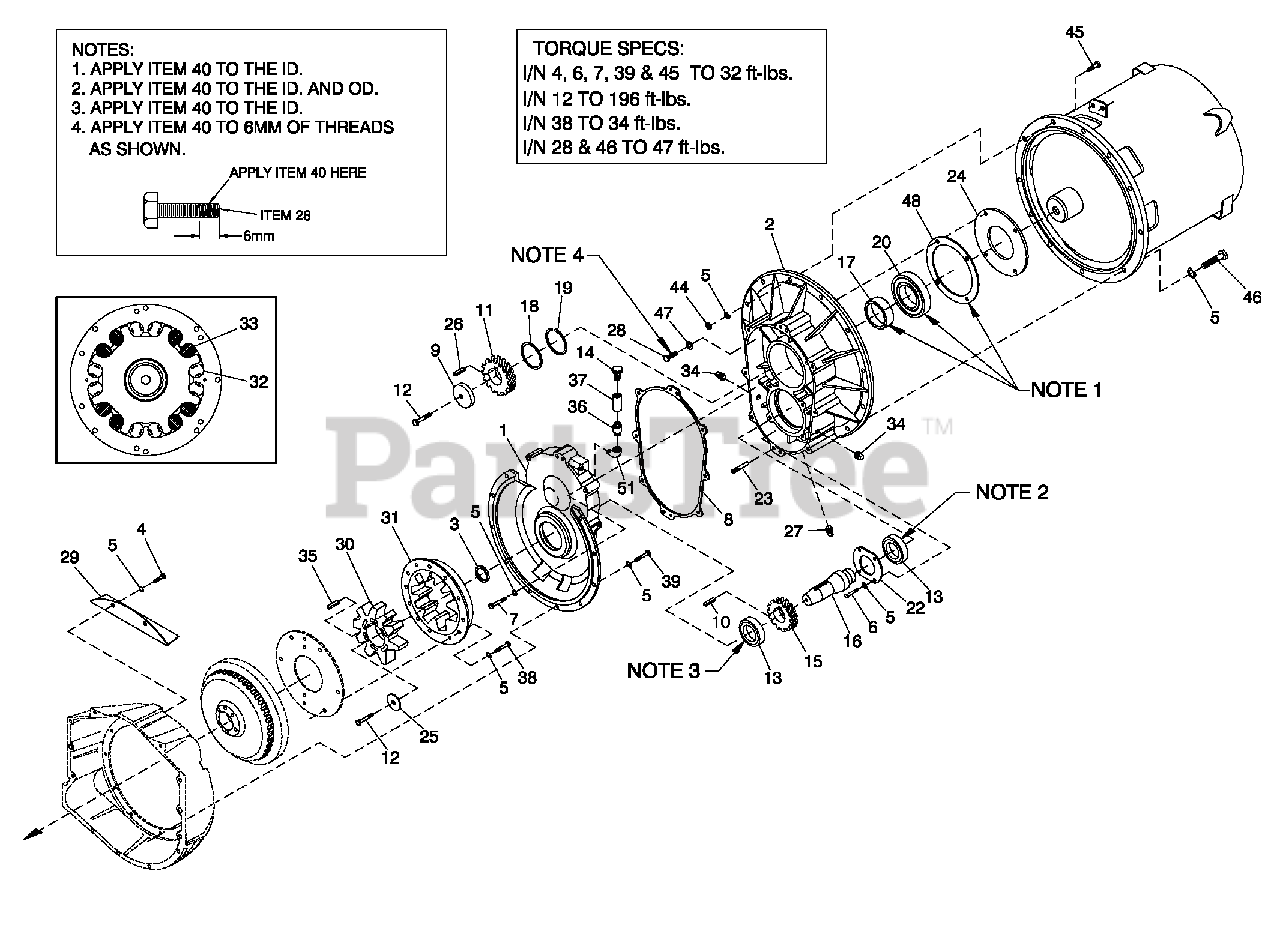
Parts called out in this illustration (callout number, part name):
1	GEAR CASE ENG. MACHINED
2	GEAR CASE ALT. MACHINED
3	SEALOIL
4	S CREW HHC M10l1.5X 20 G8.8
5	WASHER LOCK M10
6	S CREW HHC M10l1.5X 25 G8.8
7	S CREW HHC M10l1.5X 70 G8.8
8	GASKET 390 GEAR BOX
9	S PACER .69 X 2.75 X .37 ST/ZNC
10	KEY 1 0 X 1 6 X 4 6
11	GEAR OUTPUT 1.65:1
12	SCREW HHC M16-2.0X 35 G10.9
13	BALLBRG65X 120X23
14	BREATHER
15	GEAR INPUT 1.65:1
16	GEAR INPUT 2:1 50HZ390
17	SHAFT 390 INPUT GEAR
18	COLLAR HARDENED
19	SEALOIL
20	SNAP RING INT 120MM
22	BEARING #6213 SEALED
23	PLATE INTRNLBRG RET
24	PIN DOWEL M8X 24
25	PLATE BEARING THRST
26	SPACER STRESSPROOF
27	KEY 1 0 X 1 6 X 4 0
28	PLUG PIPE 3/8"MAGNETIC
29	SCREW HHFC M10-1.5X 25 G10.9
30	COVER GEARBOX GUARD
31	COUPLING INNER DRAWN
32	COUPLING OUTER MACHN
33	DAMPER GB CPLRVIBRA
34	DAMPER GB CPLRVIBRA
35	PLUG STD PIPE 3/8 STEEL SQ HD
36	KEY 1 0 X 1 6 X 5 0
37	NIPPLE PIPE3/8NPTX 3-1/2
38	COUPLING FULL 3/8-18
39	SCREW HHC M10l1 .5X 25 G8.8
40	RETAINING COMPOUND
44	NUTHEXM10-1.5G8 YEL CHR
45	SCREW HHC M10l1 .5X 60 G8.8
46	SCREW HHC M10l1 .5X 40 G10.9
47	WAS HER FLAT M10 S EALING COPPER
48	GASKET SEAL PLATE 390 G B
50	THREADLOCK AND SEALANT
51	ELB OW 90DSTREET3/8
